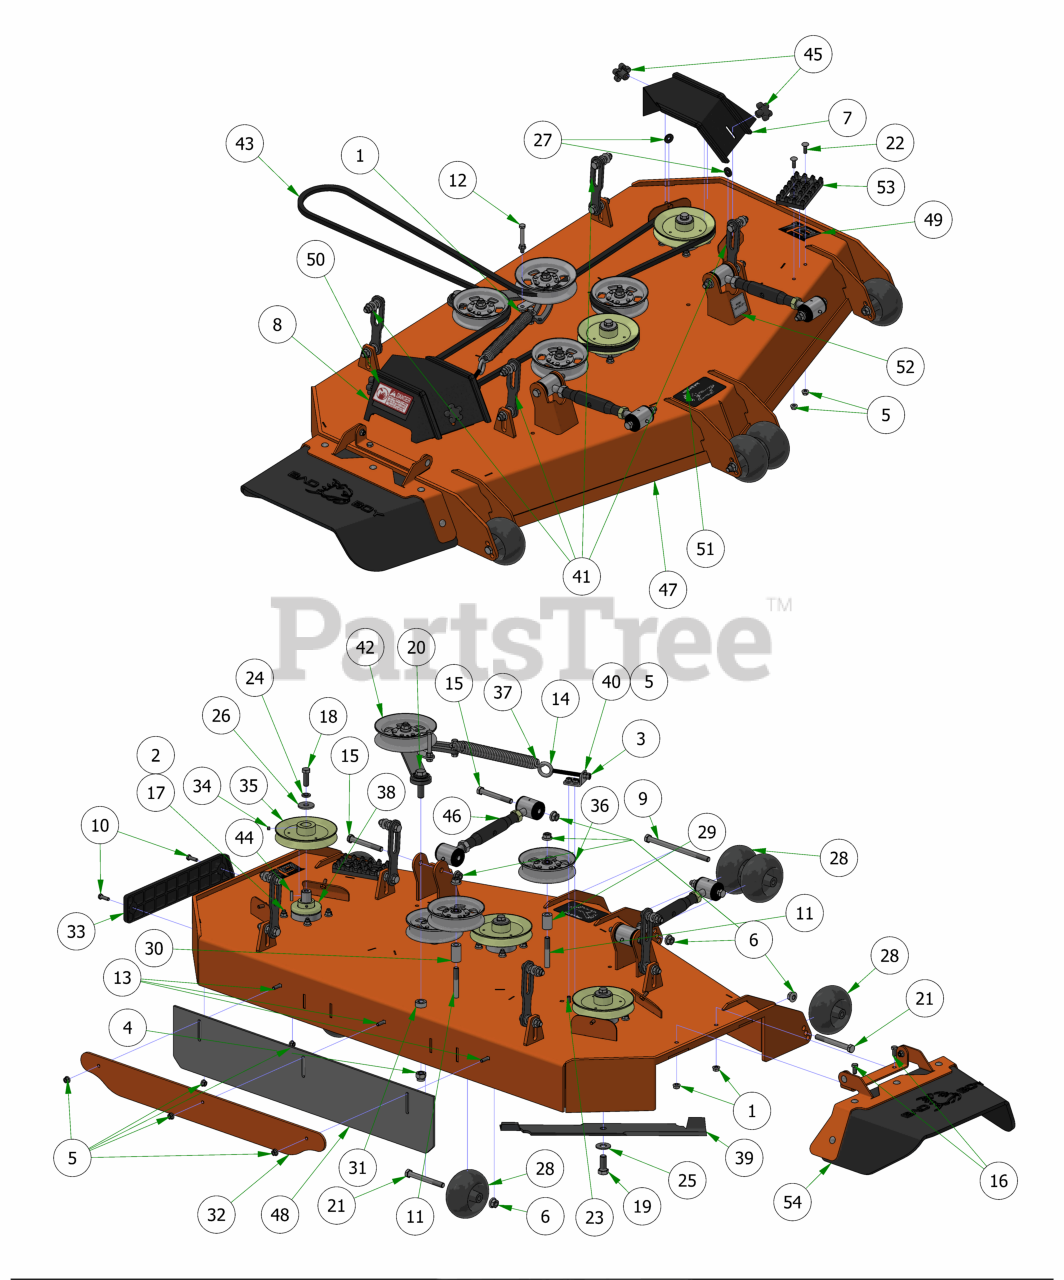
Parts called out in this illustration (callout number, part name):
1	3/8-16 HEX SERRATED FLANGE NUT HARD/ZINC
2	3/8-16 NYLON INSERT FLANGE LOCKNUT (GR.F) ZINC
3	3/8-16 HEX NUT ZINC
4	5/8-11 NYLON INSERT LOCKNUT ZINC
5	5/16-18 NYLON INSERT FLANGE LOCKNUT ZINC
6	1/2-13 NYLON INSERT FLANGE LOCKNUT ZINC
7	2019 61" Outlaw Gen2 Pulley Cover Left
8	2019 61" Outlaw Gen2 Pulley Cover Right
9	1/2-13 X 8 HEX CAP SCREW GR 5 ZINC
10	5/16-18 X 1 HEX CAP SCREW (GR.5) ZINC
11	1/2-13 X 3-1/2 HEX FLANGE BOLT (GR.8) ZINC
12	3/8-16 X 3 HEX CAP SCREW (GR.5) ZINC
13	5/16-18 X 1-1/4 CARRIAGE BOLT ZINC
14	4" 3/8-16 Eye Bolt
15	1/2-13 X 4 HEX CAP SCREW (GR.8) ZINC YELLOW
16	3/8-16 X 3/4 HEX CAP SCREW (GR.5) ZINC
17	3/8-16 X 1-1/2 HEX CAP SCREW (GR.5) ZINC
18	1/2-20 X 1-1/2 HEX CAP SCREW (GR.5) ZINC
19	5/8-18 X 1-1/2 HEX CAP SCREW (GR.8) ZINC YELLOW
20	5/8-11 X 2-1/2 HEX CAP SCREW (GR.5) ZINC
21	1/2-13 X 4-1/2 HEX CAP SCREW (GR.5) ZINC
22	5/16-18 X 1 CARRIAGE BOLT (GR.8) ZINC
23	5/16-18 X 7/8 CARRIAGE BOLT ZINC
24	1/2 SPLIT LOCKWASHER (GR.8) ZINC/YELLOW
25	5/8 USS FLAT WASHER (1-3/4" OD) GR.8 ZINC YELLOW
26	1/2 BELLEVILLE WASHER (1-5/8 OD X .140 THK) ZINC
27	.360 ID X .983 OD X .120 THICK FLAT WASHER NYLON BLACK
28	2019 Deck Wheel
29	.502 ID X .750 OD X 1.500 Long Spacer
30	1 3/4" Pulley Spacer
31	5/8 SOLID SHAFT COLLAR (W/1 SET SCREW) ZINC
32	61 Bolt in Baffle Deck v2 Stripping Plate
33	REVISED TRIM BUMPER_20180226
34	5/16-24 X 1/4 SOCKET SET SCREW (CUP PT) PLAIN
35	6 1/4" Drive Pulley
36	5-3/4 Idler Pulley
37	2019 Outlaw Gen2 Deck Spring
38	OUTLAW SPINDLE ASSEMBLY
39	61" High Lift Fusion Blade
40	2019 Deck Eye Bolt Tab
41	Deck Hanger Assembly
42	2019 Renegade Deck Idler
43	Deck Belt for 61" Renegade
44	1/4 X 1 SQ MACHINERY KEY 1018 STL PLN
45	5/16" Knob
46	Turnbuckle Assembly (M20-2.5)
47	2019 Sloped 61" Deck
48	R Series Rubber For Deck
49	61" Deck Decal
50	Danger Decal-Spindle/Discharge
51	2019 Renegade Deck Belt Route Decal
52	Deck Impact Patent Decal 9591803
53	Deck Step Assembly
54	2019 Outlaw Gen2 Chute Assembly
